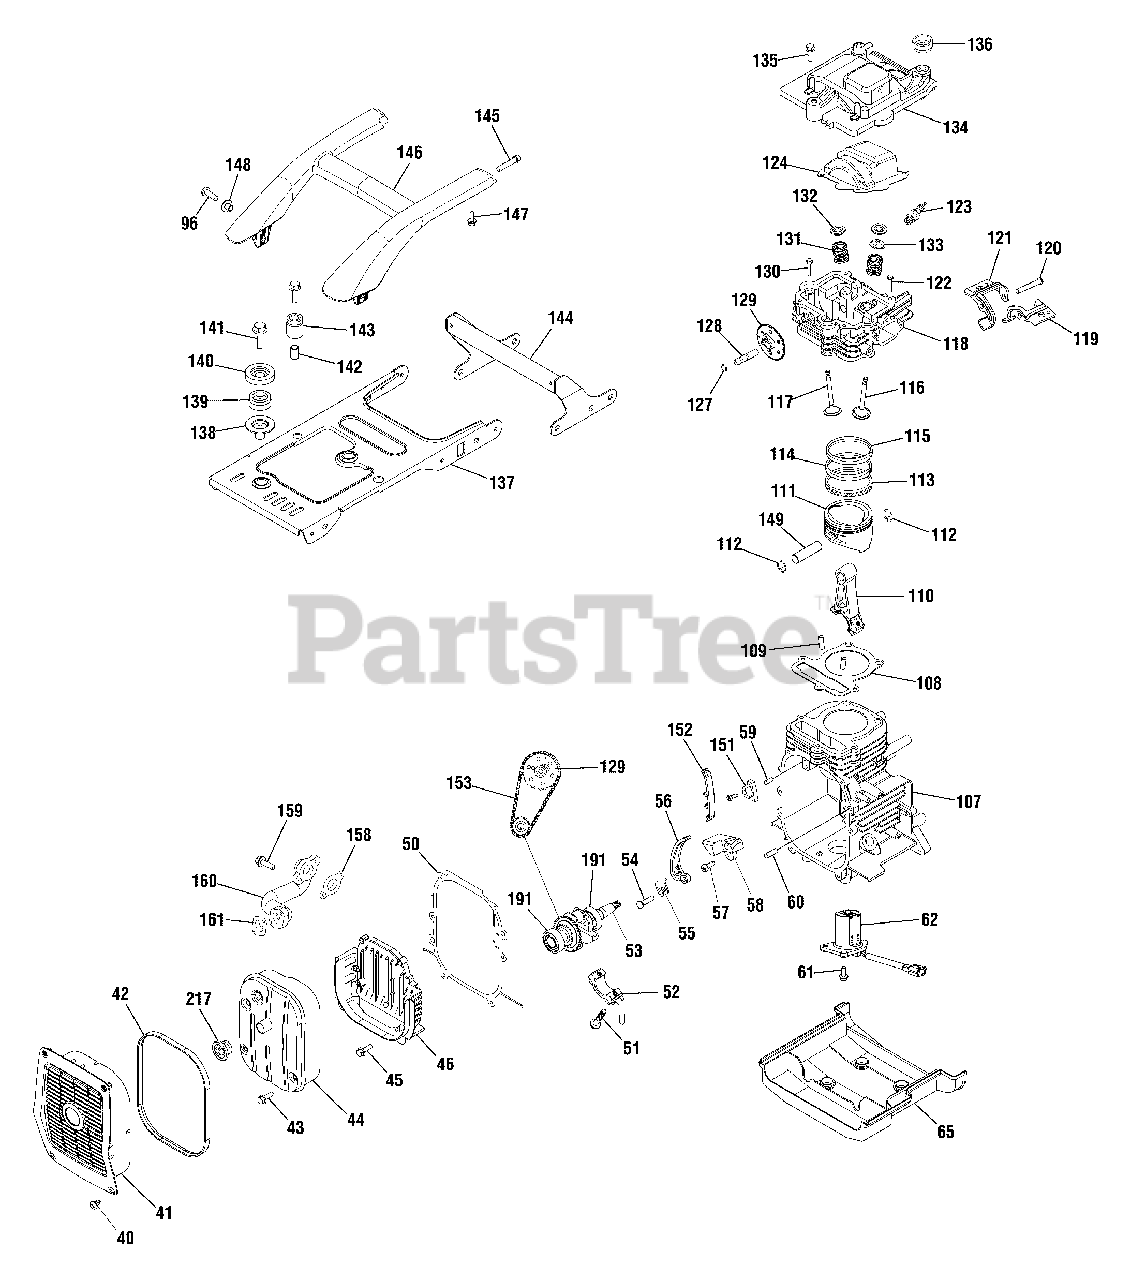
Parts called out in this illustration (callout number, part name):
40	SCREW
43	BOLT-M6 x 75
44	MUFFLER
45	BOLT-M6 x 30
46	COVER-CRANKCASE
50	GASKET-CRANKCASE
51	ROD
52	COVER
53	CRANKSHAFT
54	PIN
55	SPRING
56	ARM-TENSION
57	SCREW
58	BRACKET
59	PIN
60	PIN
61	BOLT-M5 x 14
65	COVER
96	SCREW
107	CRANKCASE
108	GASKET
109	PIN
110	ROD
111	PISTON
112	RETAINER-PIN
113	RING
114	RING
115	RING
116	VALVE-INTAKE
117	VALVE-EXHAUST
118	CYLINDER HEAD
119	ARM-INTAKE VALVE
120	PIN
121	ARM-EXHAUST VALVE
122	BOLT-M8 x 50
124	BLOCK
127	O-RING
128	PIN-SHAFT
129	CAM-ASSEMBLY
130	BOLT-M8 x 70
131	SPRING
132	SEAT-VALVE
133	SEAL-VALVE OIL
134	COVER-CYLINDER
135	BOLT-M6 x 25
136	MOUNT-VIBRATION
138	MOUNT-VIBRATION
139	BUSHING
140	GASKET
141	BOLT-M8 x 30
142	BUSHING
143	MOUNT-VIBRATION
145	BOLT-M5 x 25
147	SCREW
149	PIN-PISTON
151	BRACKET
152	BRACKET
153	CHAIN
159	BOLT-M6 x 20
160	PIPE-MUFFLER
191	BEARING
217	ARRESTOR-SPARK
